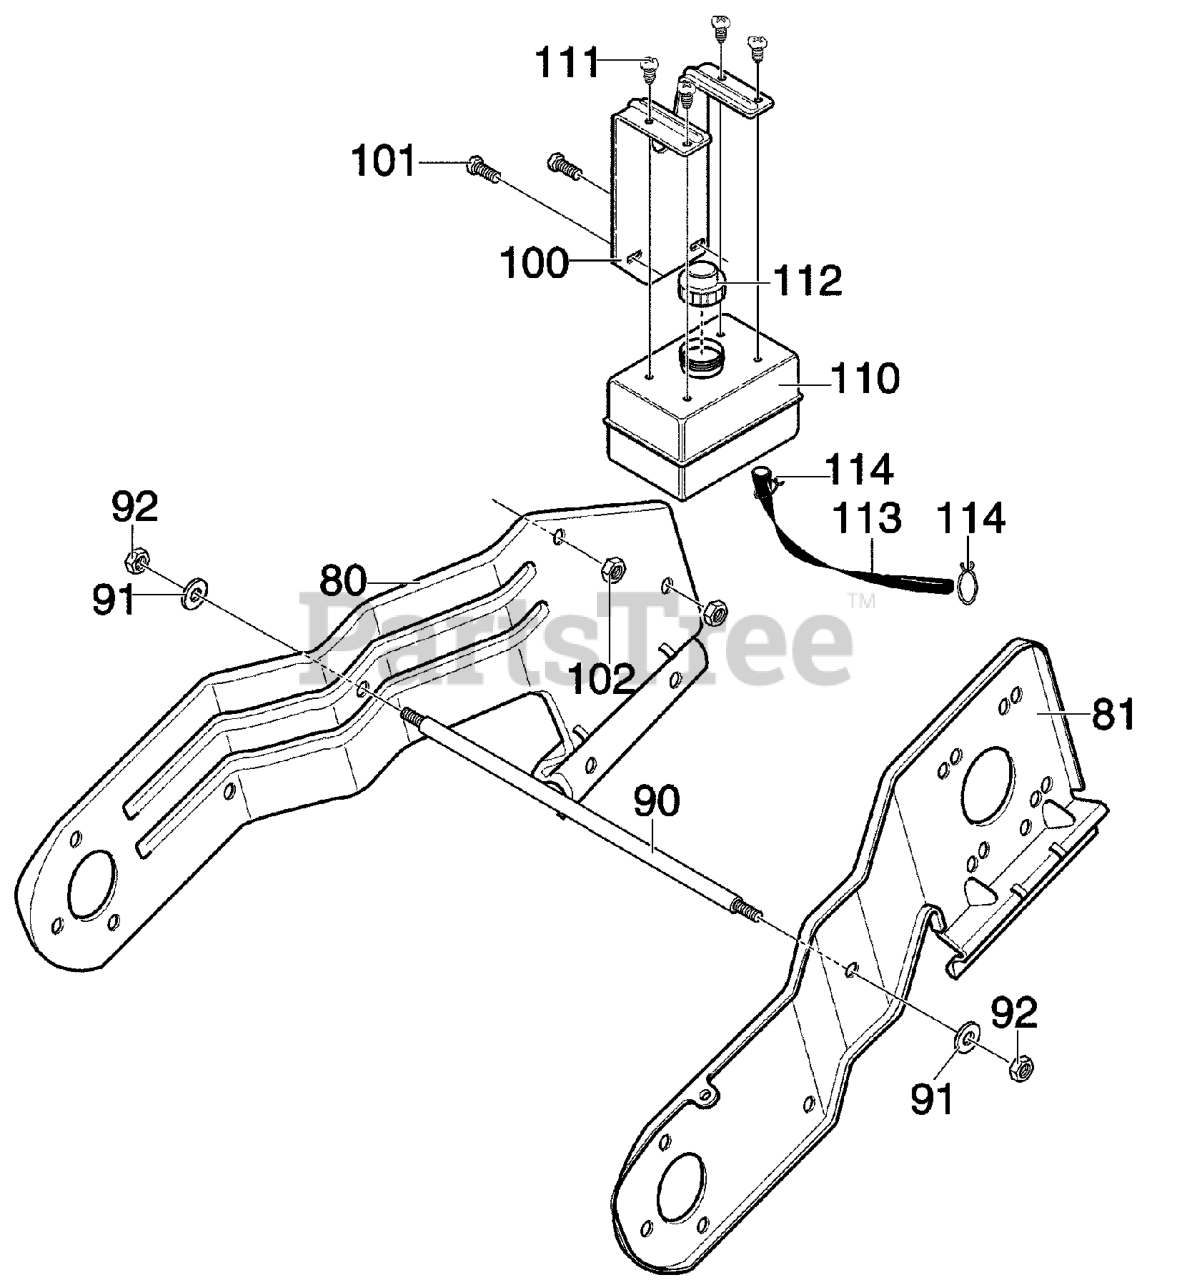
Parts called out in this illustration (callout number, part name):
80	FRAME SIDE SUPPORT RH
81	FRAME SIDE SUPPORT LH
90	ROD, SUPPORT
92	NUT, 3/8-16
100	BRACKET, GAS TANK
101	SCREW, 1/4-20X.75
102	NUT, 1/4-20
110	TANK, FUEL
111	SCREW
112	CAP, GAS-RED
113	TUBING 11.50 IN.
114	CLAMP, FUEL LINE
